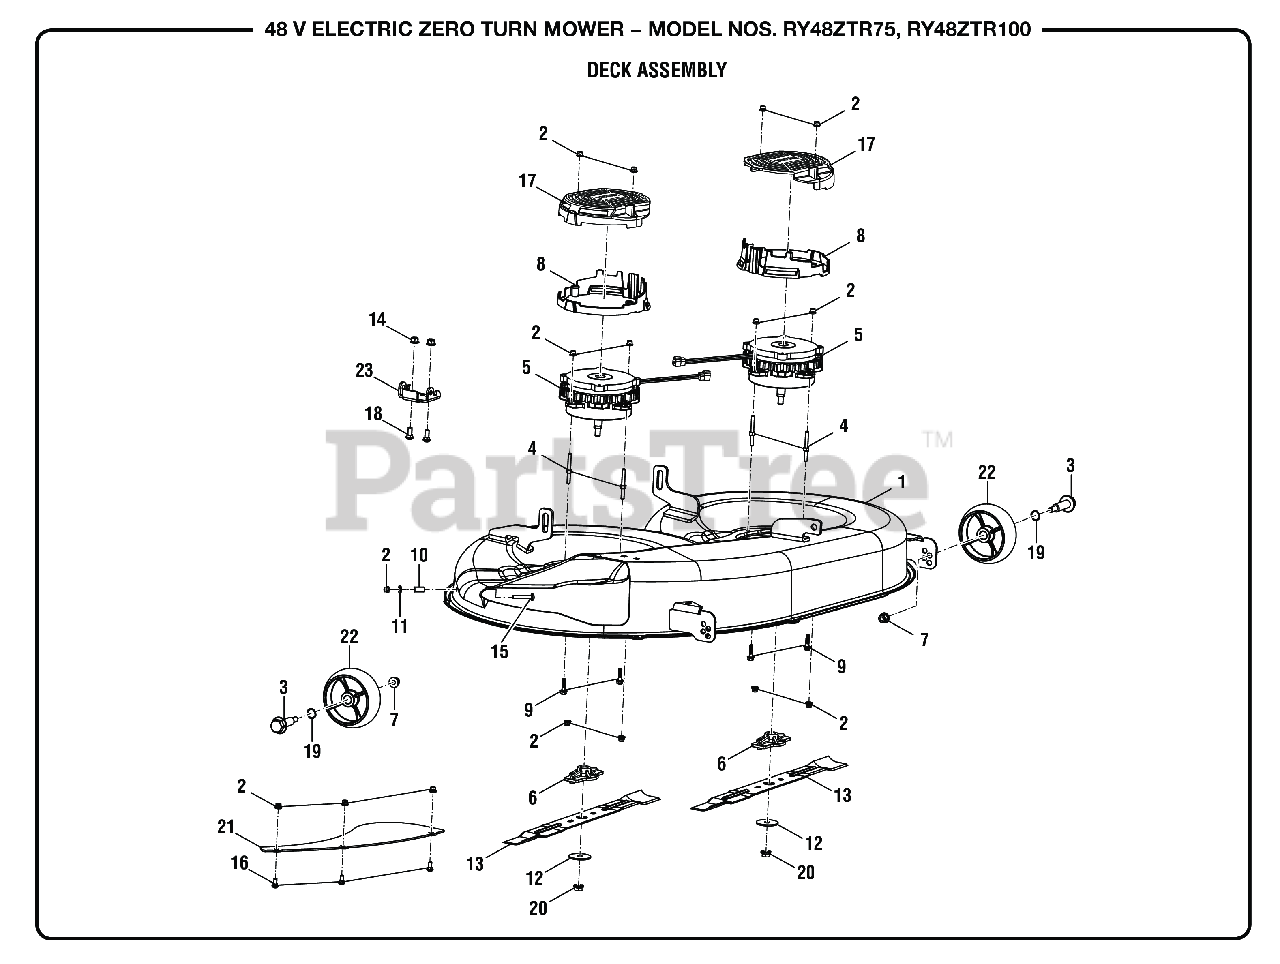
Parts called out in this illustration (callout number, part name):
1	Deck, 42 in
2	Flange Lock Nut (M6 x 1.00)
3	Shoulder Bolt (M10 x 70 mm)
4	Threaded Stud (M6 x 35 mm)
5	Deck Motor
6	Blade Adapter
7	Lock Nut (M10 x 1.5 mm)
8	Deck Motor Cover, Bottom
9	Flange Bolt (M6 x 25 mm, Hex Hd.)
10	Deck Bagger Chute Mounting Shaft
11	Washer (OD18 x ID6.4 x 1.6t)
12	Blade Retainer Washer
13	21 in. Blade
14	Flange Nut (M8) (For Drive Motor Controller V)
15	Screw (M6 x 40, Soc Hd.)
16	Carriage Bolt (M6 x 16 mm)
17	Deck Motor Cover, Top
18	Carriage Bolt (M8 x 20 mm)
19	Spring Washer (OD20.5 x ID17 x 0.3t)
20	Flange Lock Nut (M10 x 1.25)
21	Deck Baffle (42 in.)
22	Front Deck Roller Wheel (124.5 Dia.)
23	Discharge Chute Mounting Bracket
